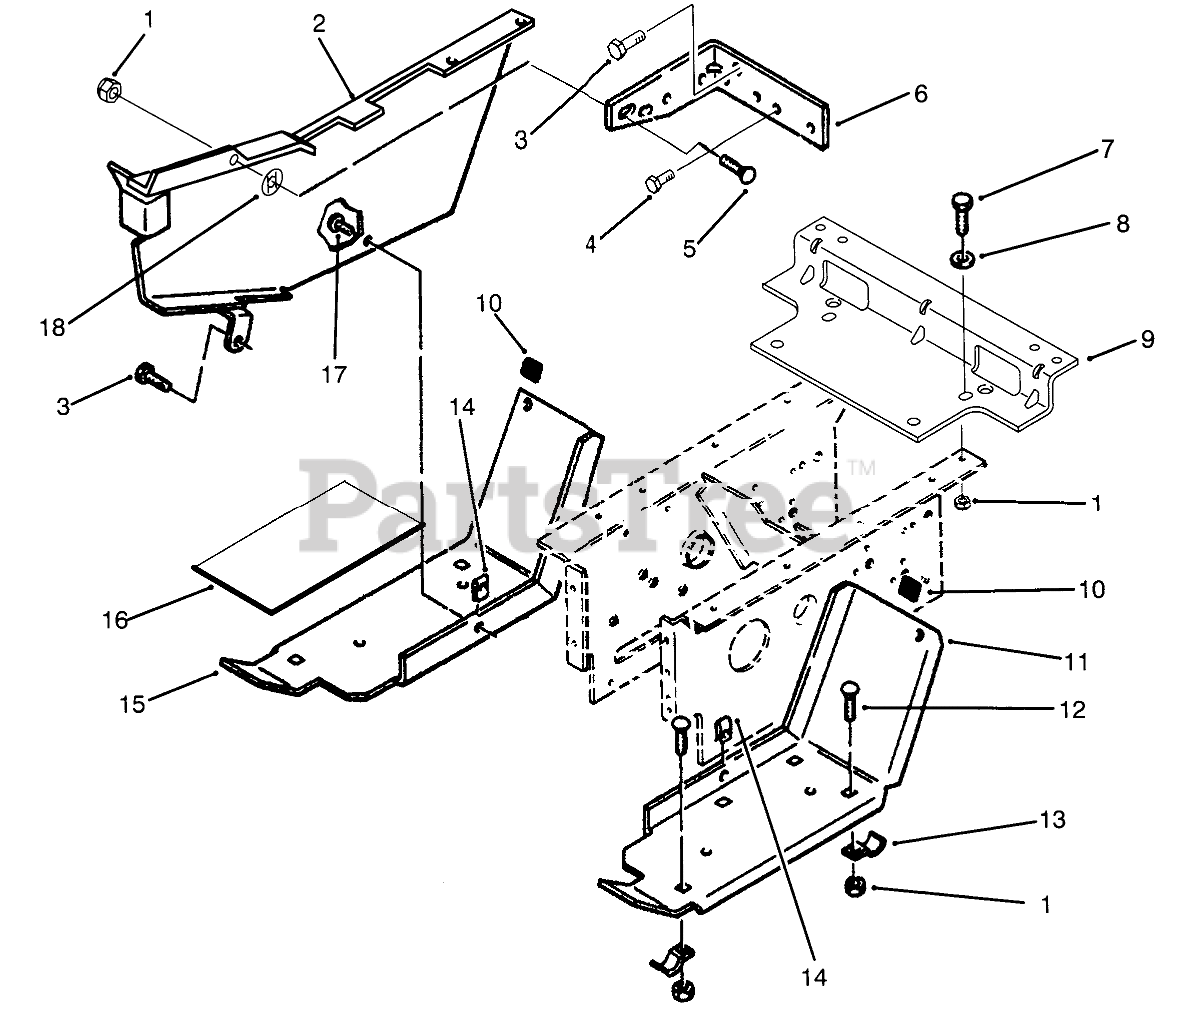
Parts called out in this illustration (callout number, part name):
1	NUT-LOCK, NI
2	GUARD - BELT WA R
3	SCREW
4	Bolt
5	BOLT-CARR
6	BRACKET-BELTB
7	SCREW-HH
8	WASHER-PLAIN
9	Bracket-Fender
10	BUMPER
11	FOOTREST LH R
12	BOLT-CARR
13	BRACKET
15	Footrest-RH
16	PAD FOOTREST
17	Screw
18	NUT-PUSH
